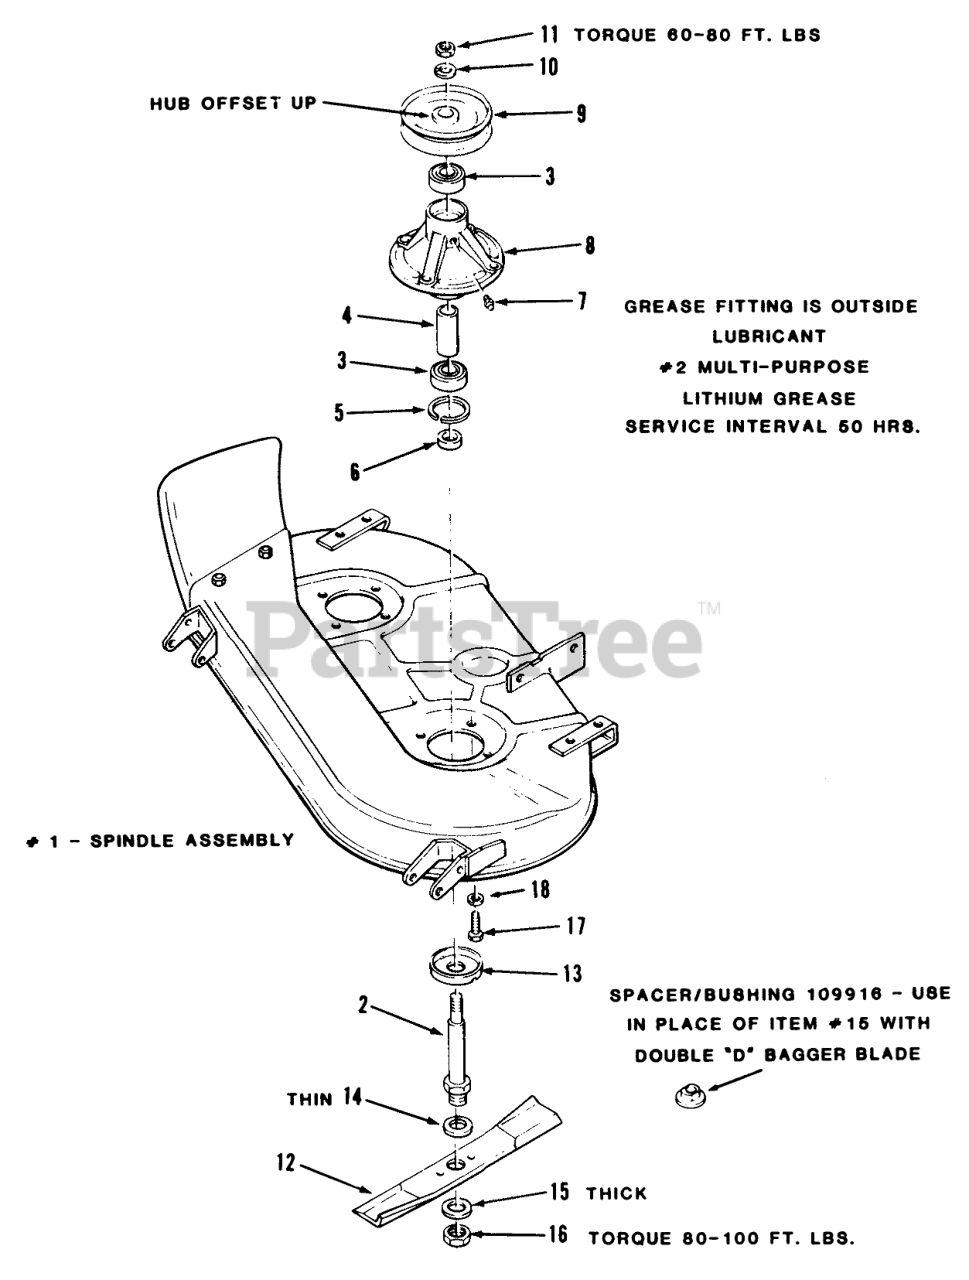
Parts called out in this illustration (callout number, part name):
2	SHAFT SPINDLE
3	BEARING-BALL
5	Ring-Snap
6	SPACER-BLADE
7	Fitting-Grease
8	HOUSING SPINDLE
9	BLADE PULLEY
10	Lockwasher
11	Nut
12	ASSY BLADE KIT
13	CUP-SPINDLE
14	Washer
15	Washer
16	Nut
17	BOLT
18	LOCKWASHER
